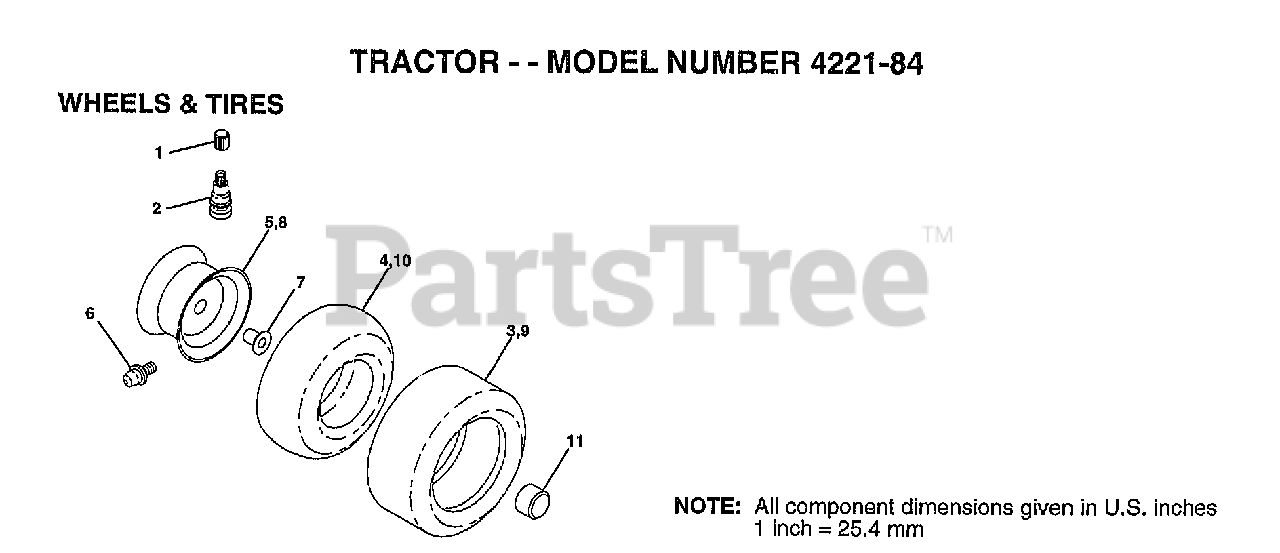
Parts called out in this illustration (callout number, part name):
1	VALVE CAP
2	VALVE STEM LT
3	"WHEEL,REAR"
4	TUBE.16X6.5/7.5-8
6	FITTING LT
7	"FLANGE, BEARING"
8	HUB CAP
10	TUBE.23X8/10-12
11	RIM.FRONT.
12	ZERK FITTING M
